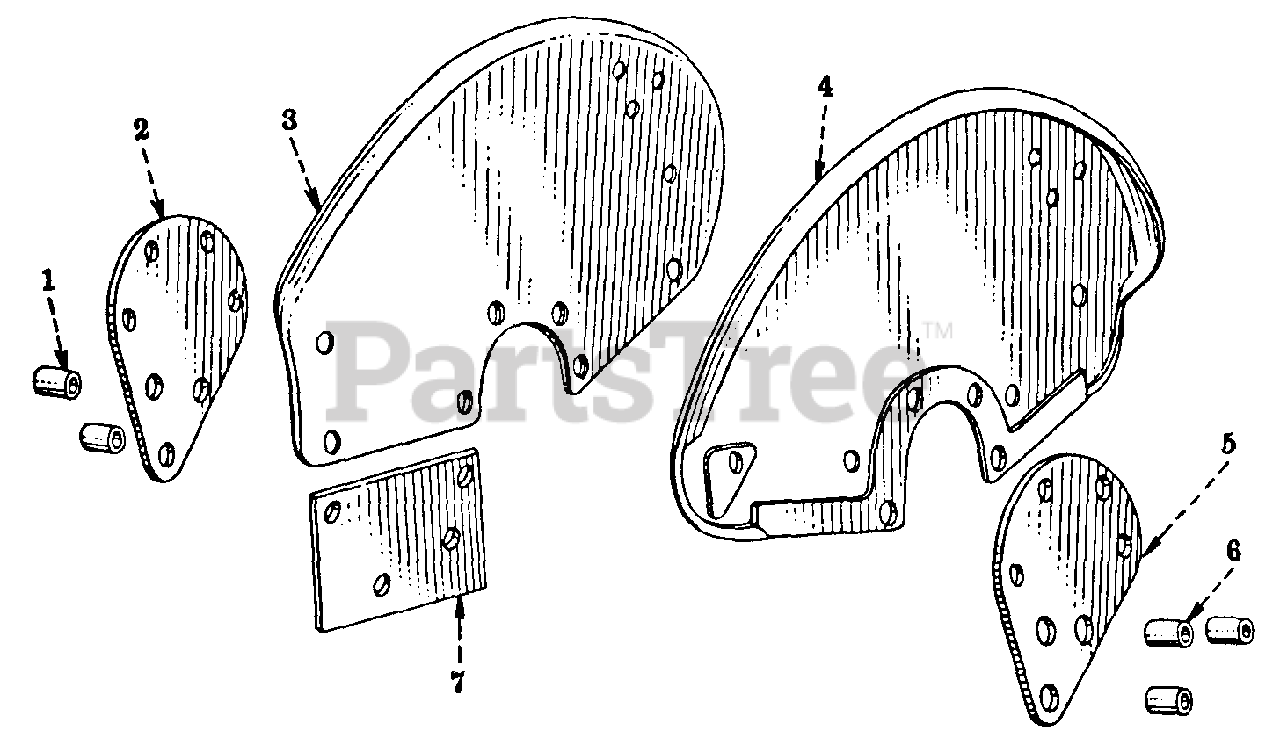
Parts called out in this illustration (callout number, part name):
1	SPACER, FENDER SUPPORT PLATE 1-1/2 IN. LONG
1	SPACER, FENDER SUPPORT PLATE 15/16 IN. LONG
2	PLATE, FENDER SUPPORT
3	FENDER ASSY, RH REAR
4	FENDER ASSY, LH REAR
5	PLATE, FENDER SUPPORT
6	SPACER, FENDER SUPPORT PLATE 1-1/2 IN LONG
6	SPACER, FENDER SUPPORT PLATE 15/16 IN LONG
7	BRACE, RH FENDER
